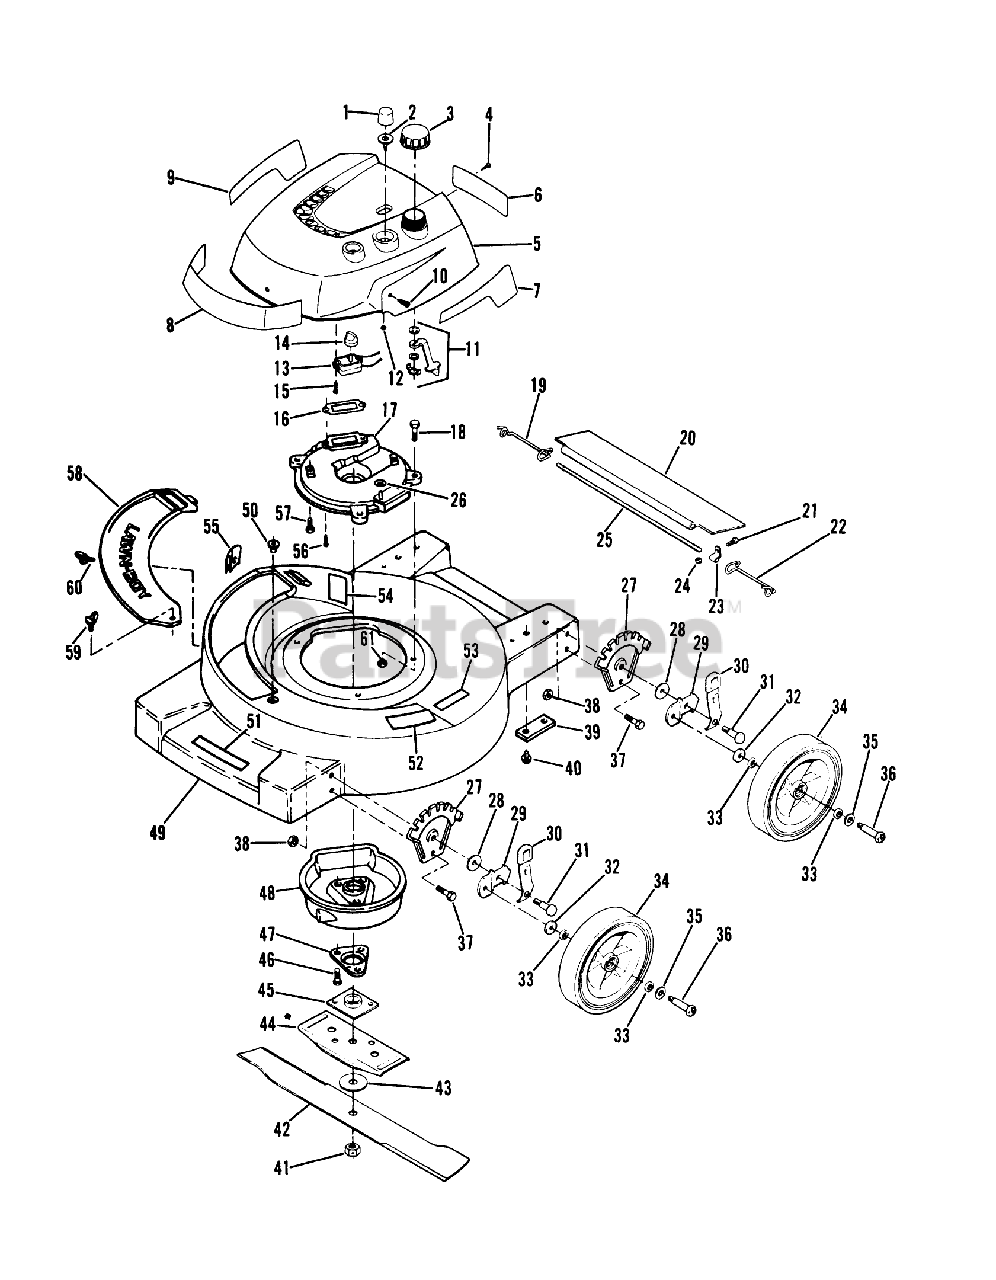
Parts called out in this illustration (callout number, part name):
4	SCREW S
10	SCREW S
12	LOCKNUT S
17	PLATE,MUFFLER F
18	SCREW
19	SPRING;TRAILING SHIELD RH
20	SHIELD
22	SPRIG T/SHLD ASOC
23	CLAMP ROD KMC
24	LOCKNUT E
25	ROD 21" ADVANCE
26	SET SCREW F
28	WASHER
30	KNOB & SPRING
32	WASHER WROUGHT
35	SPACER
36	BOLT WHEEL
38	LOCKNUT
40	SCREW
41	NUT-BLADE
43	WASHER
45	PLATE AND COLLAR ASM
46	SCREW
47	SUPPORT F
52	PAD FOOT
56	SCREW V
58	PLATE
59	WING SCREW LAWRE
61	NUT-LOCK F
